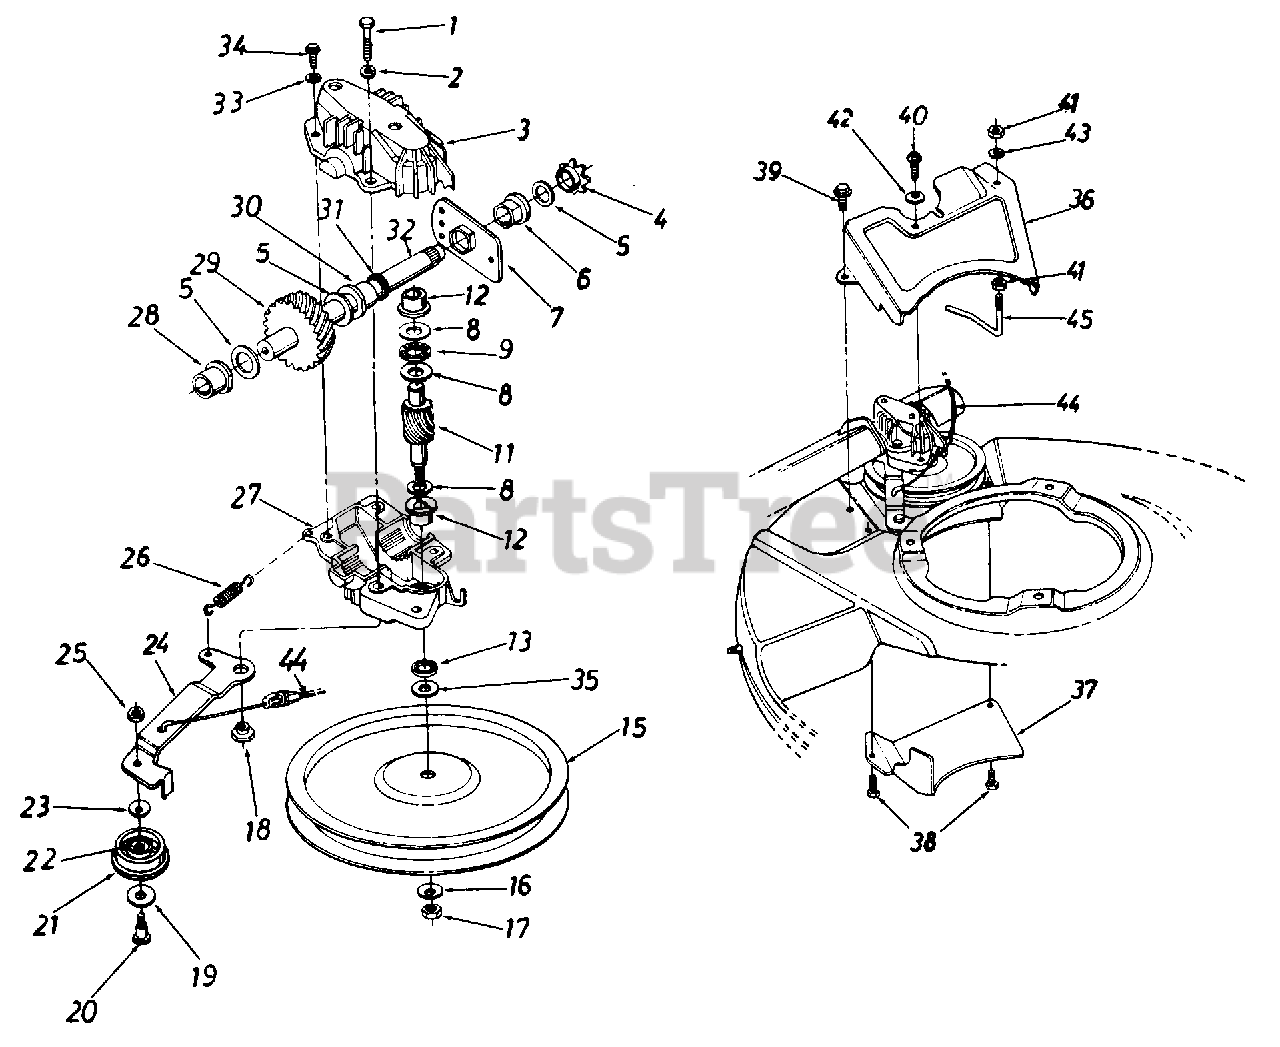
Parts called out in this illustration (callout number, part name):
1	Hex Bolt 1/4-20 x 1.25" Lg.* w/ Patch
2	L-Wash. 1/4" I.D.
3	Upper Hsg. Half
4	#48 Sprocket 7 Tooth x 1/2 Pitch
5	Fl-Wash. 518" I.D. x .030
6	Hex Flange Brg. .631" I.D.
8	Thrust Wash. .382" I.D. x .70" O.D.
9	Thrust Bearing .375" I.D. x .812" O.D.
11	11 Tooth Helical Gear
12	Flange Bearing
13	Oil Seal
15	Fl-Pulley 5.06" I.D.
16	Bell-Wash. .265" I.D. x .75"
17	Hex Nut 1/4-28 L.H. Thd.
18	Shld. Spacer .375" Dia. x .170
19	Fl-Wash. .390" I.D. x 1.0"
20	Shld. Bolt .375" Dia. x .40"
21	Fl-Idler Plastic 1.50" Dia.
22	Needle Brg. .375" x .31"
23	Bell-Wash. .265" I.D. x 75"
24	Idler Brk't. Ass'y.
25	Hex Patch L-Nut 1/4-28 Thd.
26	Extension Spring 1.12" Lg.
27	Lower Hsg. Half
28	Flange Bearing .56 Dia.
29	33 Tooth Helical Gear
30	Flange Bearing .629 Dia.
31	Oil Seal .625 Dia.
32	Gear Sprocket Shaft
33	L-Wash. #10 I.D.
34	Hex B-Tap Scr. #10 x .62n
35	Hex Washer .26" x .88"
39	Hex AB-Tap Scr. 1/4 x .50" Lg.
40	Hex B-Tap Scr. 1/4 x .62" Lg.
41	Hex Nut 1/4-20 Thd
42	Bell-Wash. .265" I.D. x .75
43	L-Wash. 1/4" I.D.
44	S.P. Cable-48" Lg.
45	S.P. Belt Guard
